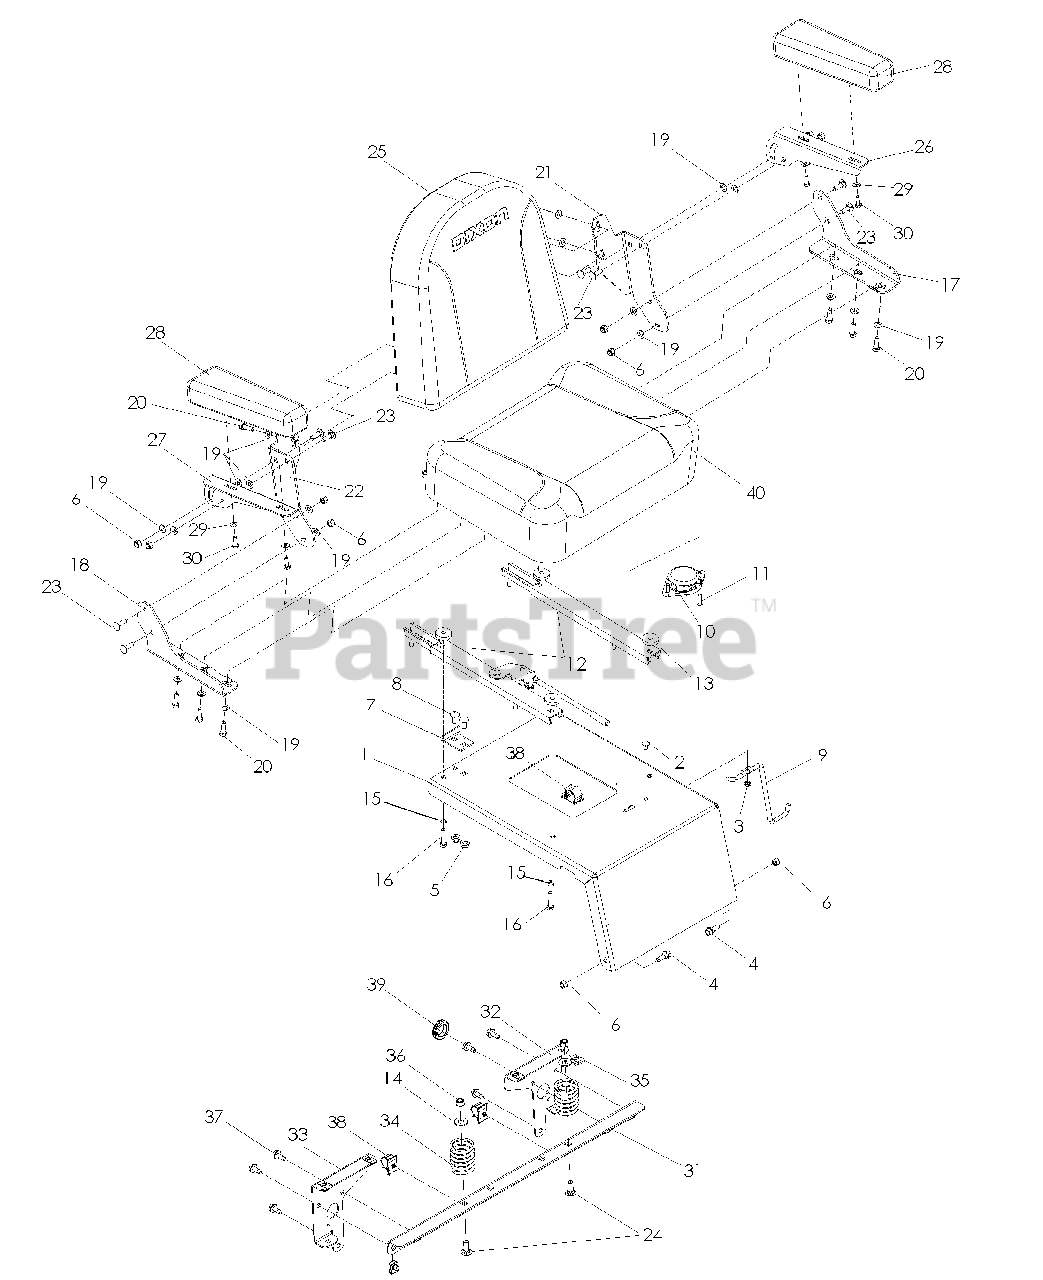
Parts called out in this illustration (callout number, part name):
1	SEAT MOUNT, W/DECALS
2	RHSNB 1/4C X 3/4
3	NUT 1/4-20 NYLOC
4	SB 5/16-18 HEX HD GD5, BLK ZN
5	5/16-18 NYLOC FLANGE NUT
6	NUT 5/16 NYLOC
7	STOP, SEAT - BLACK
8	RHSNB 5/16-18 X 3/4
9	STOP, SEAT, FORWQARD
10	SEAT SWITCH MILSCO
11	SCR 1/4-20X3/4 SLTD RDHD GR2ZD
12	SEAT SLIDE (SET)
13	WASHER NYLON
14	WASHER 3/8 FLAT
15	WASHER 5/16 LOCK
16	5/16-18X1-1/2 HHB GR5WNY
17	SEAT BOTTOM BRKT LH
18	SEAT BOTTOM BRKT RH
19	FLAT WASHER 5/16 SAE
20	5/16-18X1 HHB G5W/NY
21	SEAT BACK BRKT LH
22	SEAT BACK BRKT RH
23	RHSNB 5/16C X 1
24	RHSNB 3/8C X 1
25	SEAT BACK
26	ARM REST BRACKET LH
27	ARM REST BRACKET RH
28	ARMREST
29	WASHER 1/4 SAE
30	HCS 1/4C X 3/4 HCS
31	SUPPORT, SEAT
32	SUPPORT, LT
33	SUPPORT, RT
34	SPRING, SEAT
35	U-CLIP 5/16-18 NUT RETAINER
36	NUT 3/8-16 NYLOC
37	BOLT 5/16-18 X 3/4
38	PUSH-MOUNT WIRE CLIP
39	RUBBER GROMMET
40	SEAT BOTTOM
